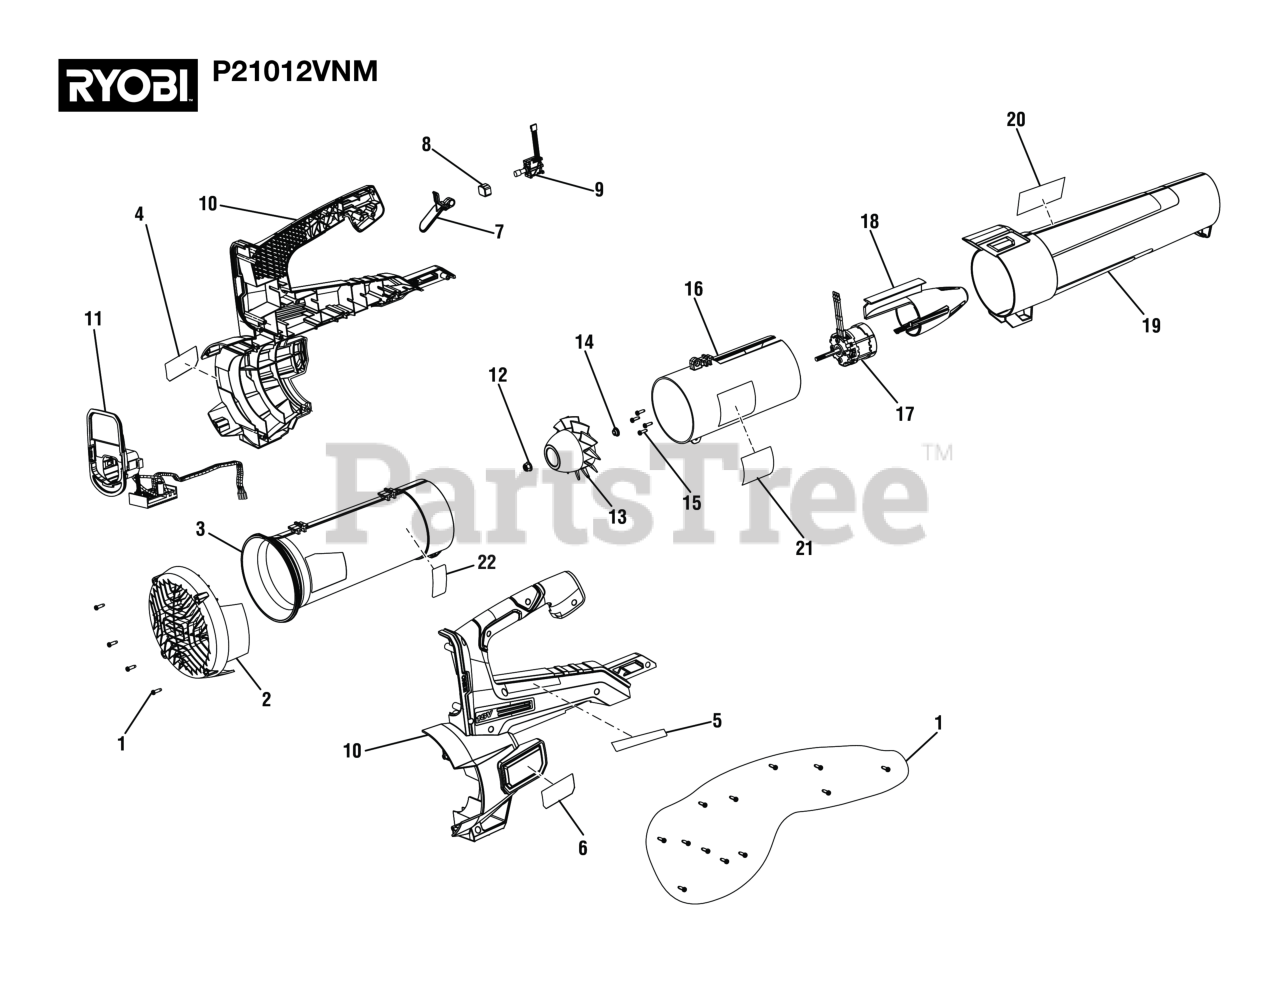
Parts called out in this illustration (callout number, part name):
1	Screw (M4 x 14 mm, T15 Torx Pan Hd.))
3	Inlet Bell Assembly
4	Logo Label
5	Icon Label
6	Data Label
8	Switch Cap
9	Variable Speed Switch
10	Housing Assembly
11	Motor Controller & Battery Foot Assembly
12	Flange Lock Nut (M6 x 1 mm)
15	Screw (M3.5 x 12 mm, T15 Torx Pan Hd.)
16	Stator Assembly
18	Nose Cone
19	Tube Assembly
20	HP Brushless Label
21	Warning Label
